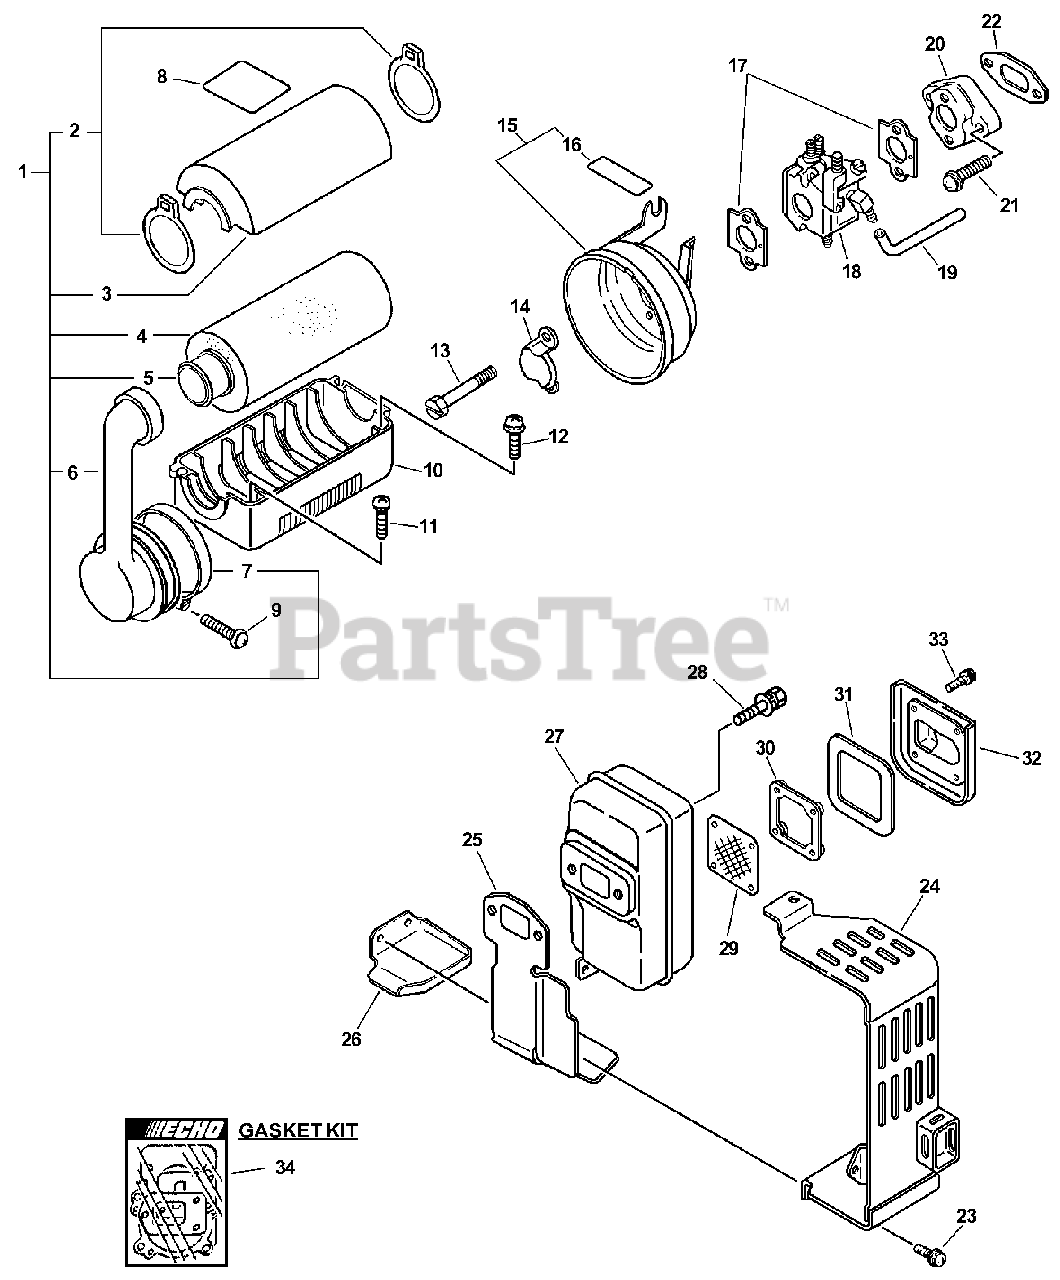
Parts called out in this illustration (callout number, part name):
1	AIR CLEANER ASSY
3	COVER, AIR FILTER
4	FILTER, AIR
5	FILTER, AIR
6	ADAPTOR, INTAKE
8	LABEL - CAUTION
9	SCREW - 5X30
10	CASE, AIR FILTER
11	SCREW - 6X15
12	SCREW - 6X20
13	SCREW - 5X55
14	PLATE, PREVENT
15	CASE, AIR FILTER
16	LABEL - CHOKE
17	GASKET, INTAKE
18	CARBURETOR WT-684
19	PIPE - IMPULSE
20	INSULATOR, INTAKE
21	SCREW - 6X25
22	GASKET, INTAKE
23	SCREW - 5X14
24	SHIELD, EXHAUST
25	GASKET, EXHAUST
26	BRACKET, MUFFLER COVER
27	MUFFLER
28	SCREW - 6X20
29	SCREEN, SPARK ARRESTOR
30	RETAINER, SCREEN
31	GASKET, EXHAUST
32	GUIDE, EXHAUST
33	SCREW - 4X16
34	GASKET KIT
